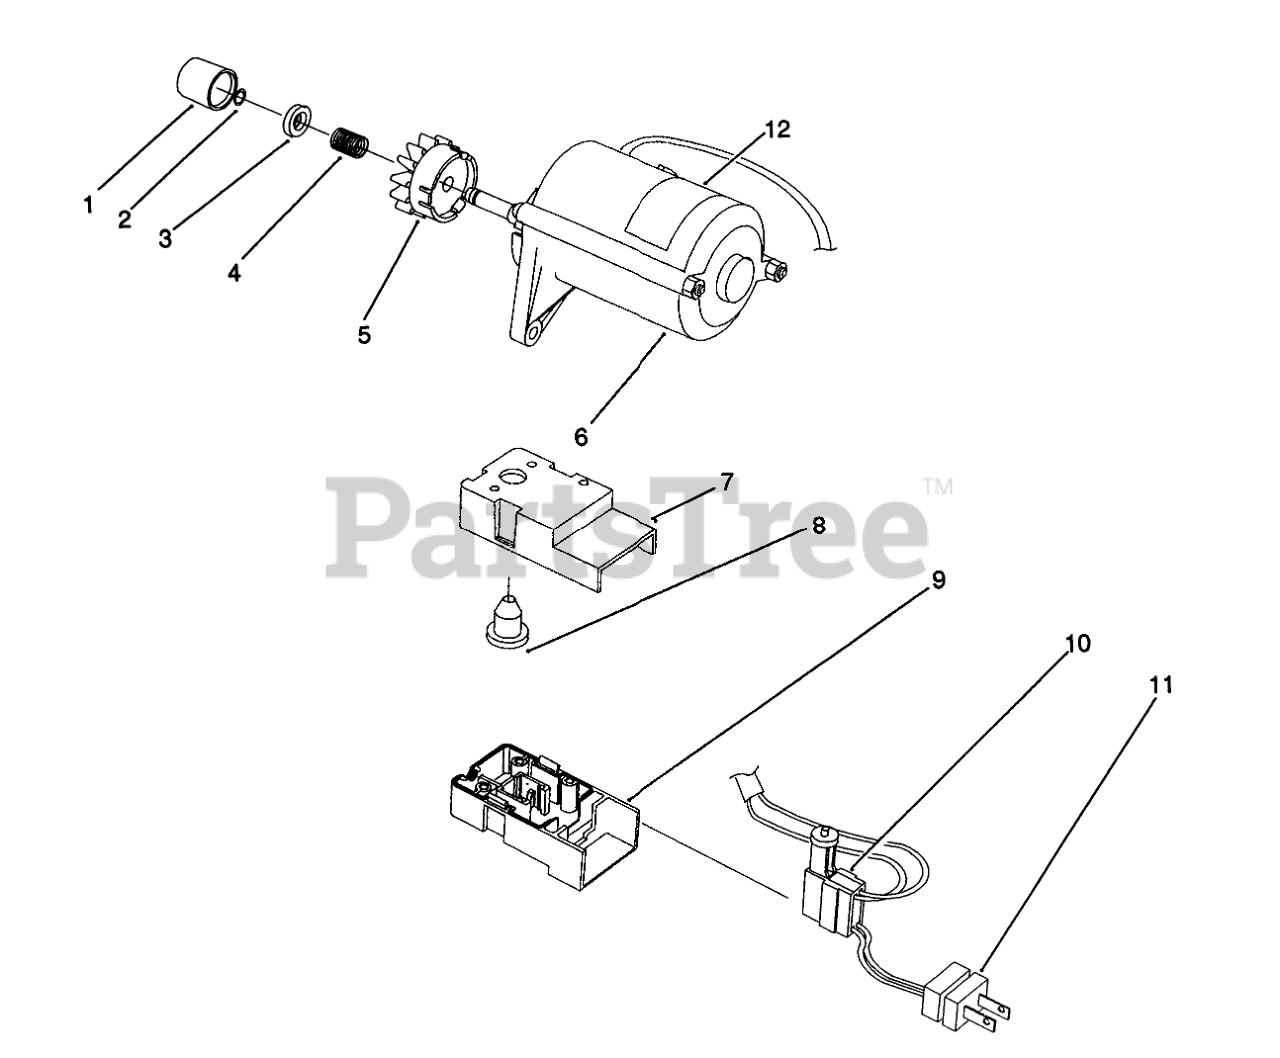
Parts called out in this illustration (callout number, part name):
1	CAP-PINION
2	RING-LOCK
3	PINION STOP
4	SPRING
5	Pinion Assembly
6	Starter Motor Assembly
7	Cap-Switch Housing
8	BOOT-SWITCH
9	OBS BASE X
10	SWITCH-STARTER
11	Plug
12	Decal-UL
